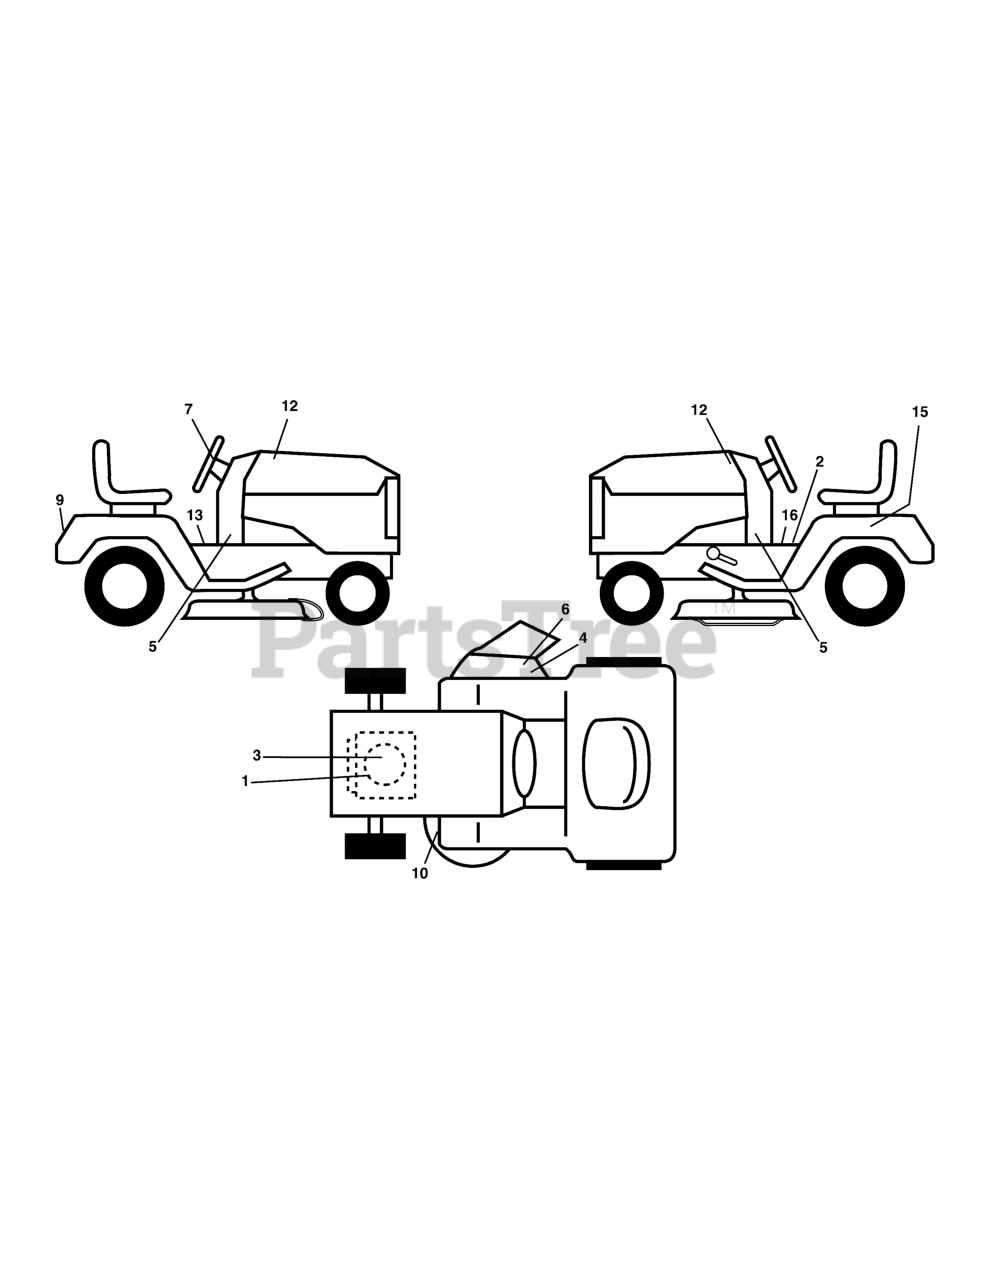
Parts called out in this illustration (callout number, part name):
1	Decal, Warning Eng Sym
2	Decal, Warning Symbols
3	Decal, Engine HP
4	Decal, Warning Cutfinger
5	** Decal, Lower Dash
6	Decal, Cutfinger
7	Decal, Ins Str Wh
9	Decal, Fender
10	Decal, V-Belt Sch.
12	Decal, Hood LH/RH Set
13	Decal, Saddle Brake Parking
15	Decal, Caution, Battery
16	Decal, Brake/Clutch Sym.
